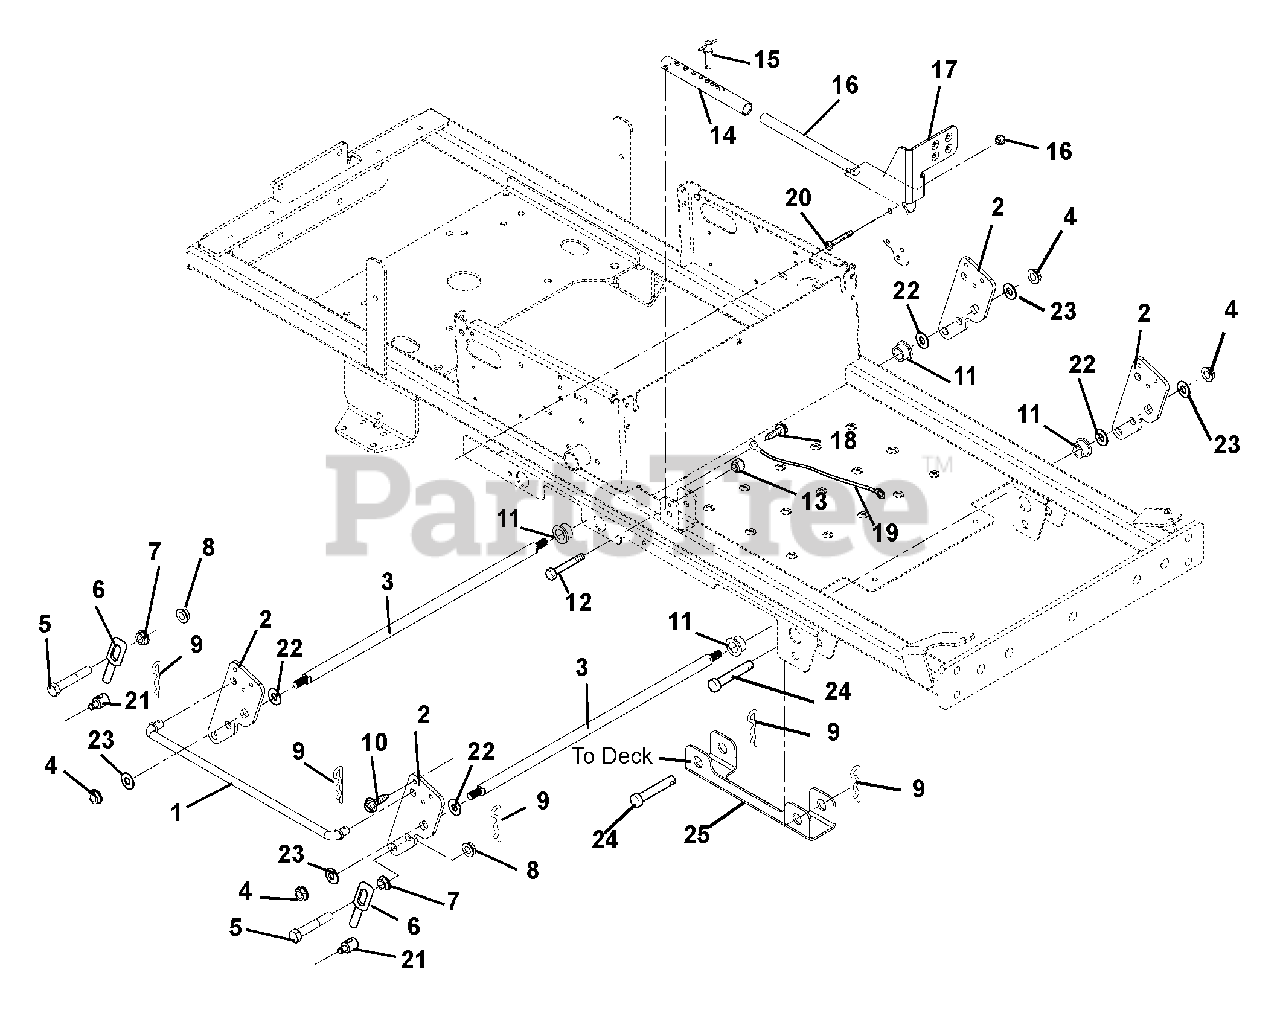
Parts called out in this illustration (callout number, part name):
1	ROD,LIFT
2	LIFT ARM
3	SHAFT, LIFT
4	NUT-HEX .250-28 YWZC
5	BLT-HEX .50-13X2.75 YZ GR8
6	DECK LINK
7	NUT-SPNLK-FLG .50-13 YWZC
8	@NUT-LK-NYL-FLG .50-13 YWZC
9	PIN, HAIR, EXT - #16 YWZC
10	@SCR-TAP .31-18X.50 HWH TR YWZ
11	BSHG-FLG .750X1.000X.625X1.250
12	@BLT-HEX .38-16X2.00 GR5 YWZC
13	@NUT-LK-NYL-FLG .38-16 YWZC
14	TUBE,LIFT STOP
15	PIN, SPRING BALL .375OD X 1.50
16	ROD,LIFT
17	PEDAL,FOOT LIFT
18	@SCR-TAP .25-20X.50 HWH TR YWZ
19	CBL,HOOD
20	@BLT-HEX .38-16X2.50 GR5 YWZC
21	TRUNNION-.50
22	WSHR-FL-STL.755X1.375X.062YWZC
23	WSHR-FL-STL .515X1.625X.250 YZ
24	PIN-CLEV .494X2.50 BRIGHT ZINC
25	CHANNEL, DECK LIFT
